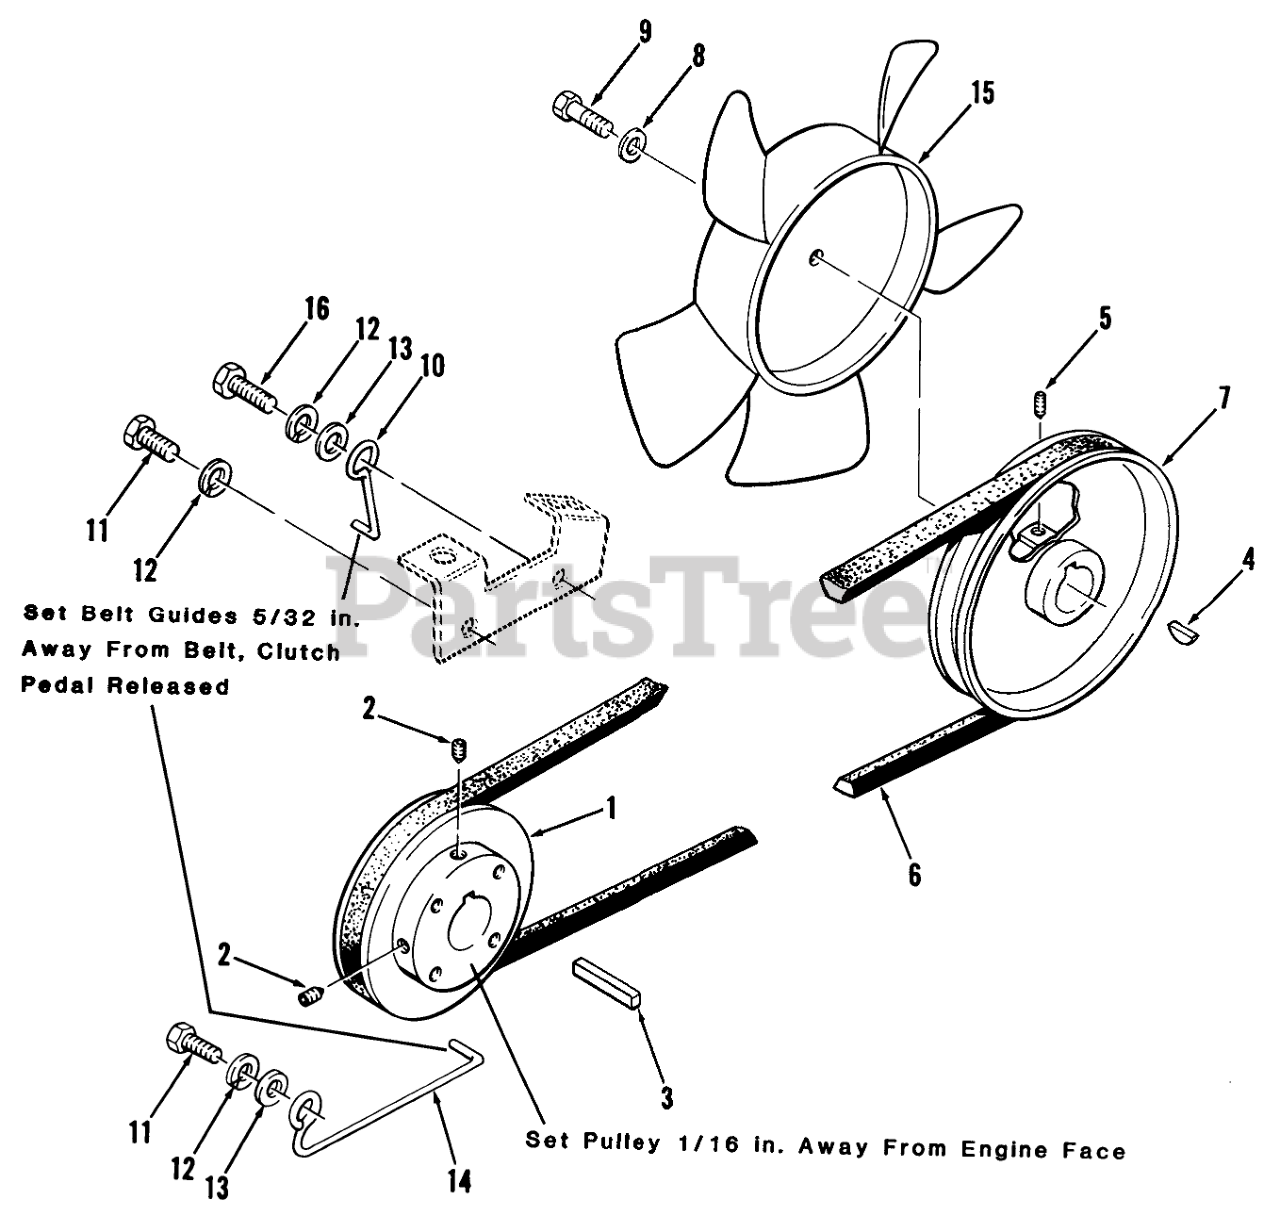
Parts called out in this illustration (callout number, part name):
1	PULLEY
2	Set Screw
4	KEY-WOODRUFF
4	KEY-HI PRO
5	Set Screw
6	V-BELT TRANS DRIVE
6	V BELT
6	Belt-Drive
7	PULLEY
7	PULLEY-TRANSMISSION
8	WASHER
9	H H C S
10	Belt Guide-Top
11	7/16-14 x 1 1/4 Bolt
11	Bolt
12	LOCKWASHER
13	WASHER
13	Washer
14	Belt Guide-Bottom
14	GUIDE-BELT
15	NYLON FAN-L-CW
16	7/16-14 x 1 1/4 Bolt
16	Bolt
